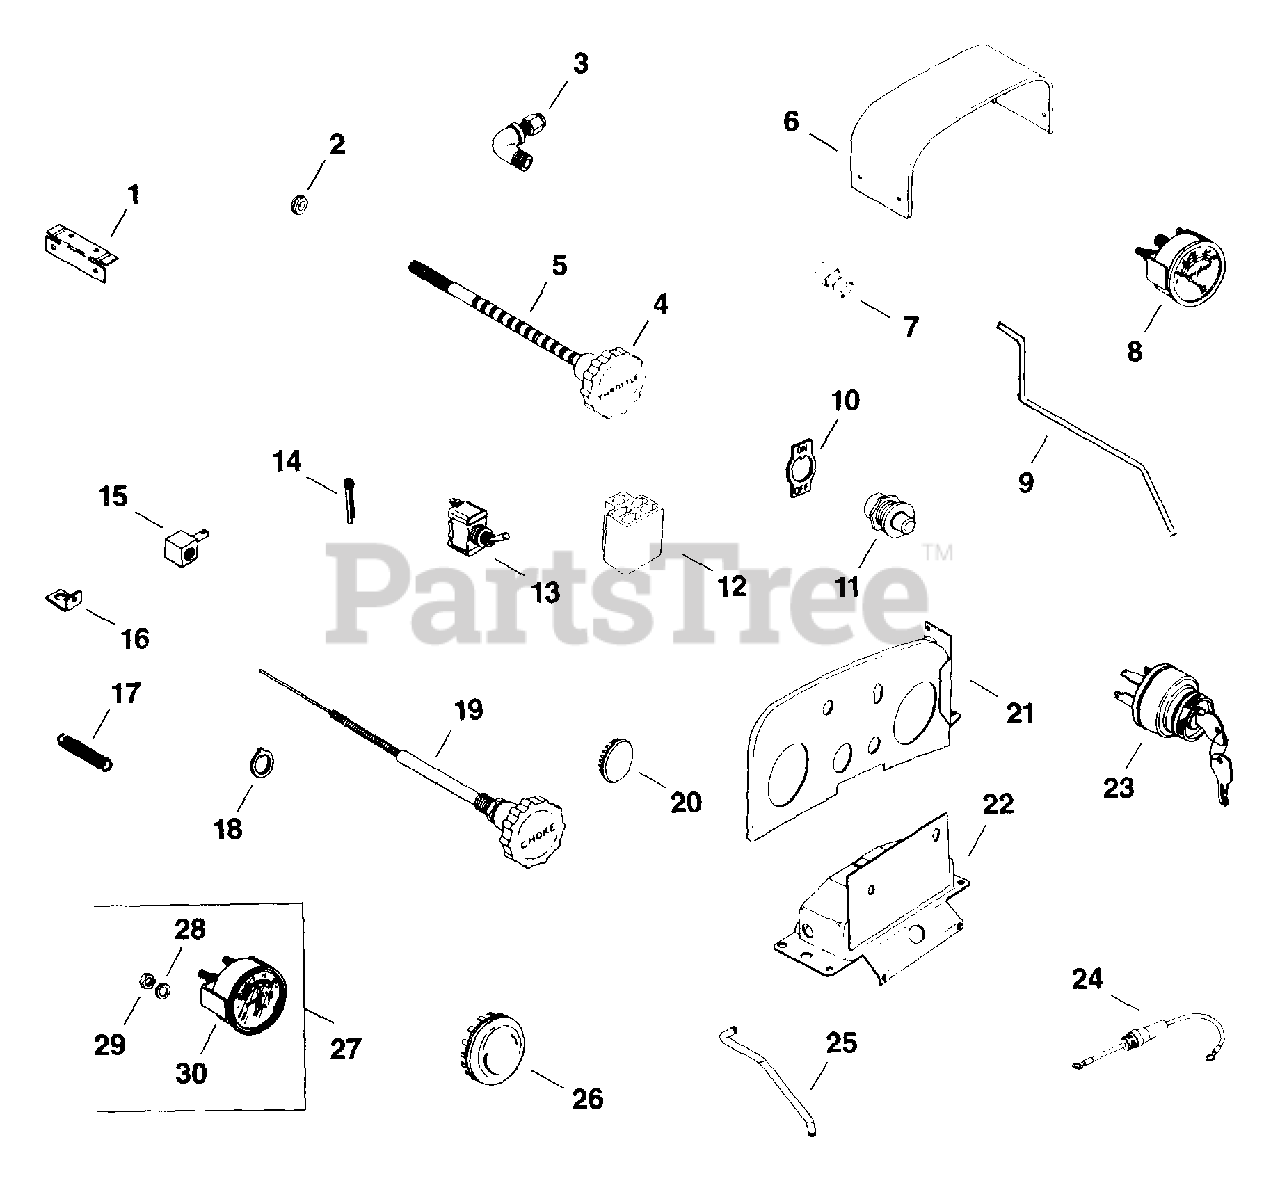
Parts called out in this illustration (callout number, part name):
4	KNOB - DISCONTINUED
7	CONNECTOR - (#DSC)
10	PLATE - DISCONTINUED
13	SWITCH - DISCONTINUED
14	PIN, COTTER USE 25 380 03-S
15	BLOCK - (#DSC)
17	SPRING - (#DSC)
18	RING -DISCONTINUED
20	PLUG 7/8 USE 25 139 25-S
